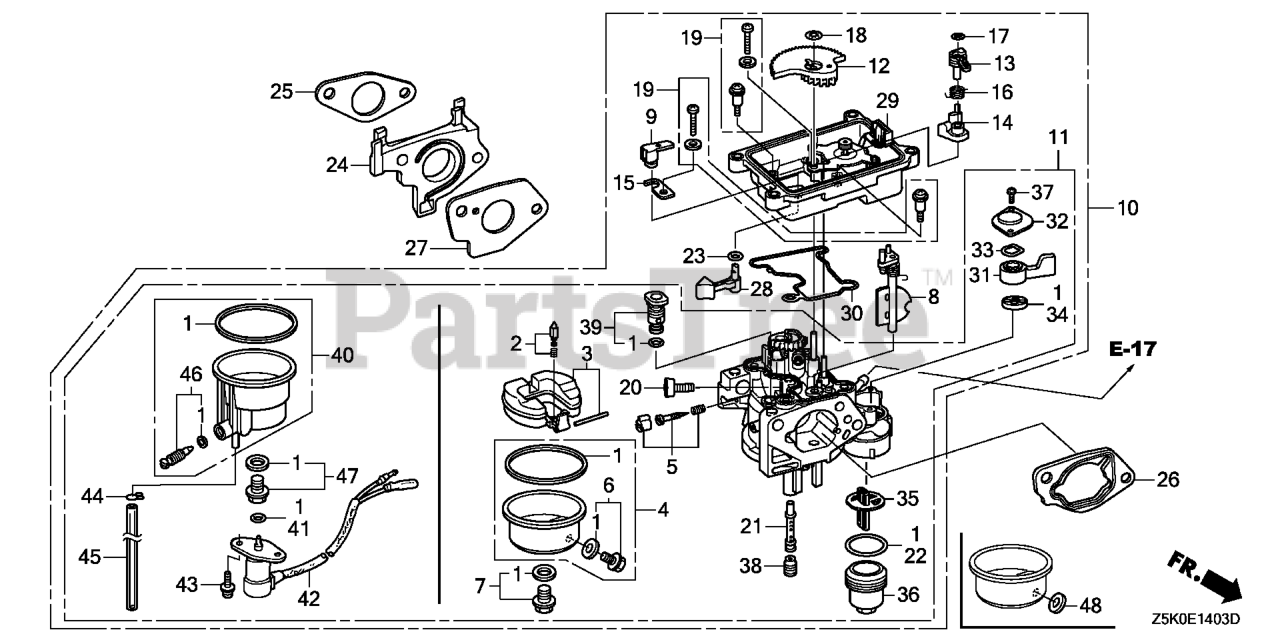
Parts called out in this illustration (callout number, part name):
1	GASKET SET (INCLUDE 16173-001-004) (INCLUDES 16173-001-004)
2	VALVE SET, FLOAT
3	FLOAT SET (CARBURETOR NO.)
4	CHAMBER SET, FLOAT
5	SCREW SET (Honda Code 4219879). (CARBURETOR NO.)
5	SCREW SET (CARBURETOR NO.)
6	SCREW SET, DRAIN
7	SCREW SET (CARBURETOR NO.)
9	ARM, MANUAL START
10	CARBURETOR ASSY. (BE90B A)
10	CARBURETOR ASSY. (BEC3A A)
11	CARBURETOR SET
12	GEAR, MIDDLE
13	ARM, CHOKE
14	LEVER, CHOKE CONTROL
16	SPRING, TORSION COIL
17	CLIP, SPECIAL
18	CLIP, SPECIAL
20	SCREW, STOP
21	NOZZLE, MAIN
22	GASKET, FUEL STRAINER CUP
23	O-RING (CARBURETOR NO.)
24	INSULATOR, CARBURETOR
25	GASKET, INSULATOR
26	SPACER, CARBURETOR
27	GASKET, CARBURETOR
28	LEVER, MANUAL START
29	CASE, MOTOR
31	LEVER, VALVE
32	PLATE, LEVER SETTING (CARBURETOR NO.)
33	SPRING, PETCOCK LEVER (CARBURETOR NO.)
34	GASKET, VALVE
35	FILTER, CUP (CARBURETOR NO.)
36	CUP, FUEL STRAINER
37	SCREW, PAN (3X6)
38	JET, MAIN (#82)
38	JET, MAIN (#85) Use up to Engine SN BE81B B.
38	JET, MAIN (#88) Use up to Engine SN BE81B B.
39	JET SET, PILOT (#40) (ADVENTURE GREEN) (CARBURETOR NO.)
48	WASHER, PLAIN (6.2X10.7 DRAIN) (CARBURETOR NO.)
